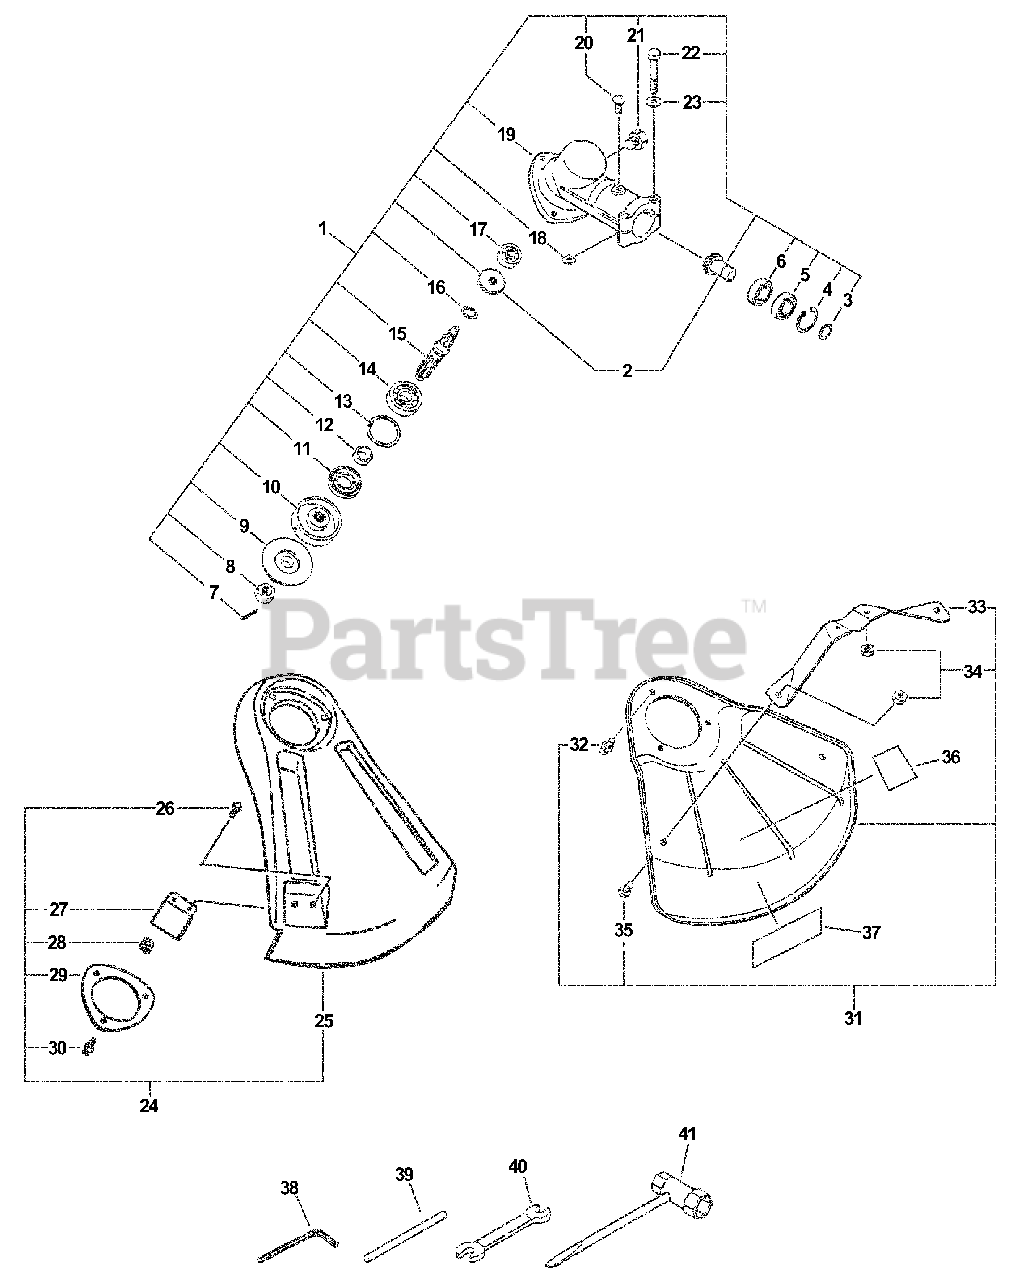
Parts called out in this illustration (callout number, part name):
1	GEAR CASE ASSY
2	GEAR SET - BEVEL
3	RING, RETAINING - 12
4	RING, RETAINING - 28
5	BEARING, BALL - 6001
6	BEARING, BALL - 6001C3
7	PIN, SPLIT - 2X22
8	NUT - 10 -- LEFT HAND
9	ADAPTOR, BLADE - LOWER
10	ADAPTOR, BLADE - UPPER
11	SEAL, OIL
13	RING, RETAINING - 32
14	BEARING, BALL - 6201
15	GEAR - SHAFT
16	RING, RETAINING - 12
17	BEARING, BALL - 6000
19	CASE, GEAR
20	SCREW - 5X10
21	BOLT - 8X8
22	BOLT - 5X40
23	WASHER - 5
24	DEBRIS SHIELD KIT - PLASTIC
25	SHIELD, DEBRIS - PLASTIC
26	SCREW - 5X16
27	KNIFE, TRIMMER LINE
29	PLATE, SHIELD
30	SCREW - 5X16
31	DEBRIS SHIELD KIT - METAL
32	SCREW - 5X10
33	BRACKET, SHIELD
34	LOCKNUT - 5
35	SCREW - 5X8
36	LABEL - DANGER
37	LABEL - ECHO
38	HEX KEY - 4mm
39	LOCKING TOOL
40	SPANNER - 8X10mm
41	T-WRENCH - 17X19mm
